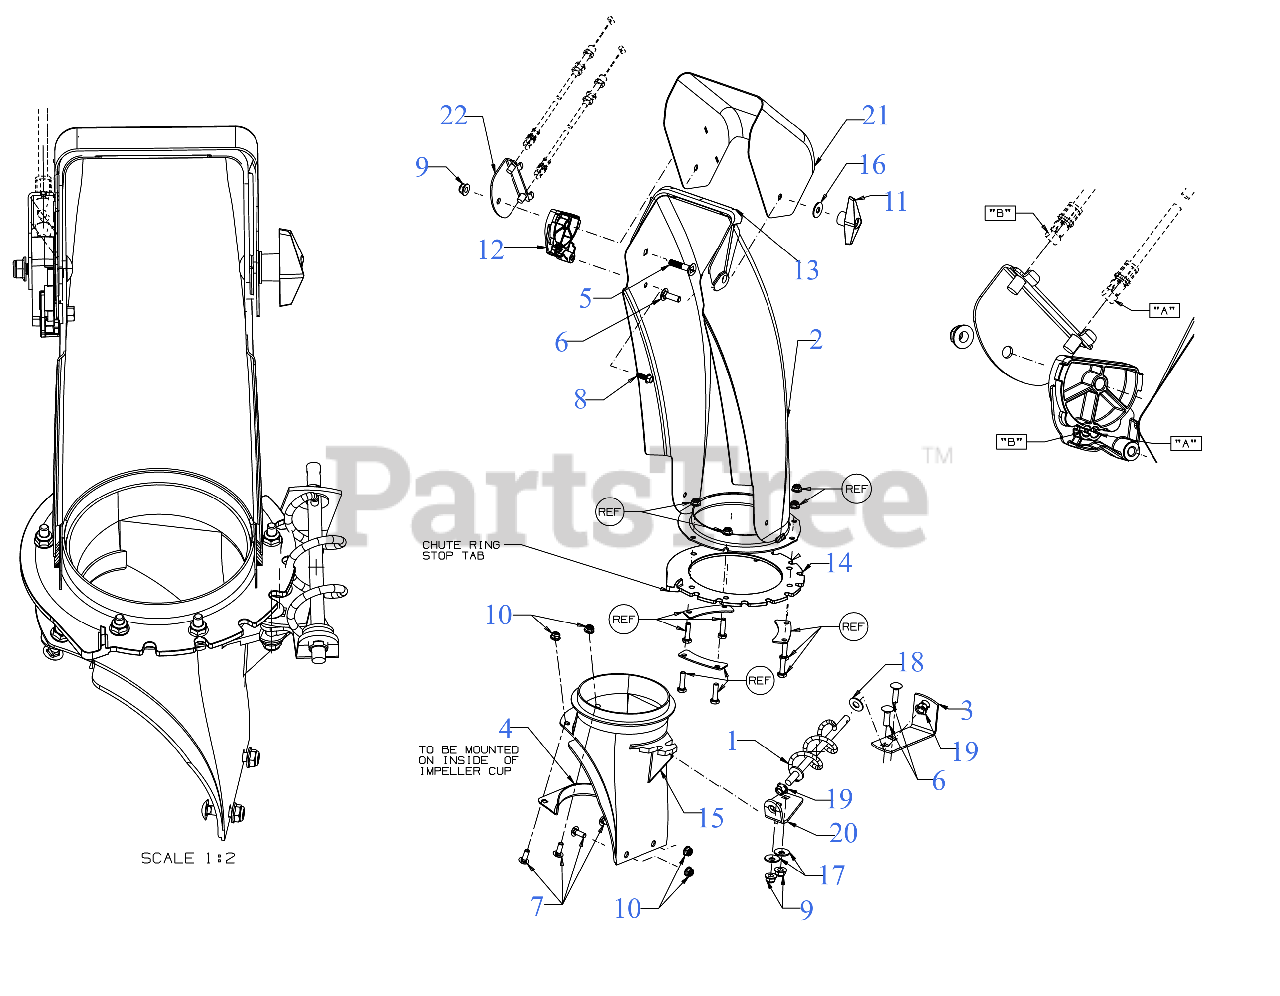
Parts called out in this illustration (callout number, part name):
1	CHUTE CRANK ASSEMBLY
2	LOWER CHUTE (POWDER BLACK)
4	CHUTE REINFORCEMENT
5	CARRIAGE BOLT 5/16-18 x 1.50
6	CARRIAGE BOLT 5/16-18 x 1.00
7	SCREW 1/4-20 x .75 GR5
8	SCREW 1/4-15 x .750
9	FLANGE LOCK NUT 5/16-18
10	FLANGE LOCK NUT
11	WING KNOB NUT
12	CHUTE TILT GUIDE
13	UPPER CHUTE ADAPTER
14	CHUTE CRANK RING
15	CHUTE ADAPTER
16	FLAT WASHER
17	BELL WASHER .337 X.867 x .057
18	FLAT WASHER.40 ID
19	BUSHING .380 ID
20	CHUTE CRANK BRACKET
